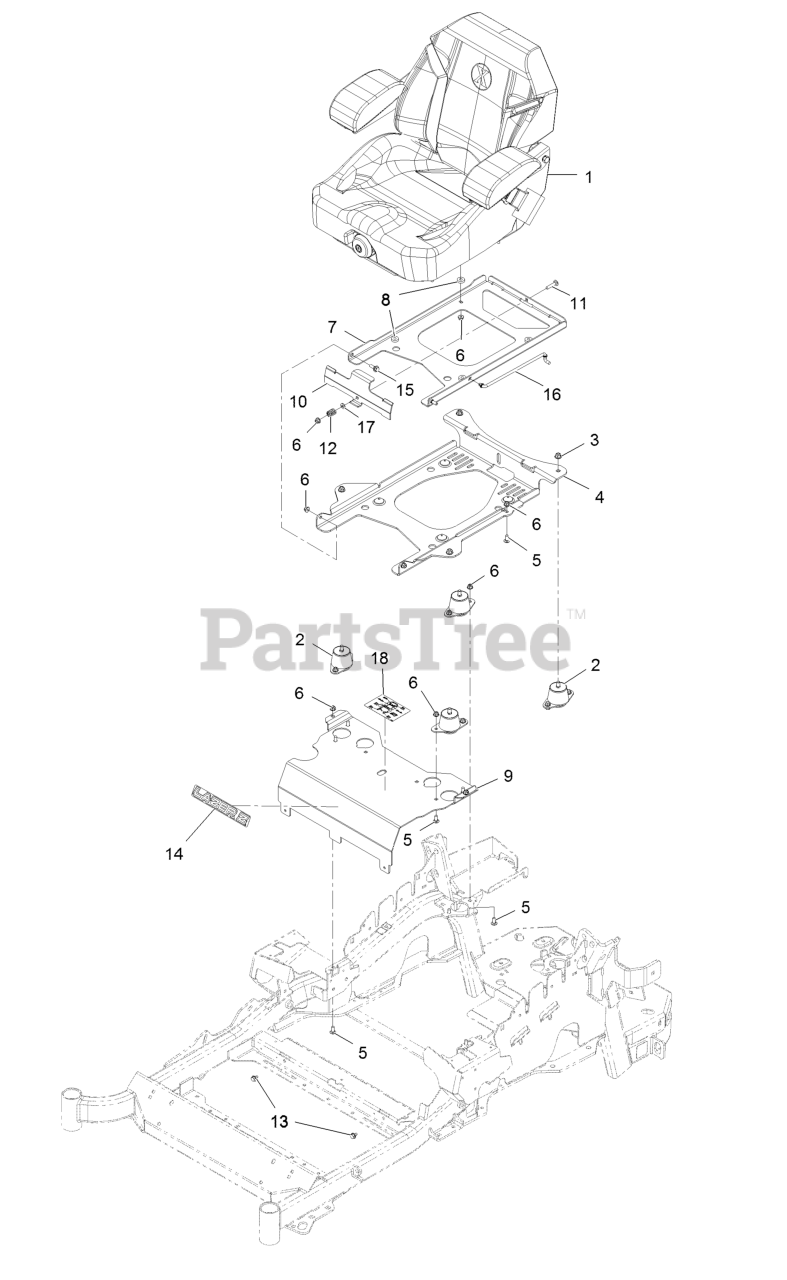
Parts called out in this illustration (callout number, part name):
1	KIT-SUSPENSION SEAT
2	ISOLATOR-SEAT
3	NUT-HF, NI
4	PLATE-TILT, SEAT SUPPORT
5	SCREW-CARR
6	NUT-HF, NI
7	PLATE-FRAME, SEAT
9	Panel-Front, Seat Mount
10	PLATE-LATCH, SEAT
11	BOLT-CARR
12	SPRING-COMPRESSION
14	DECAL, LAZER MODEL
15	SCREW-SHOULDER
16	ROD-PROP
17	WASHER-PLAIN
18	DECAL-SERVICE AID
